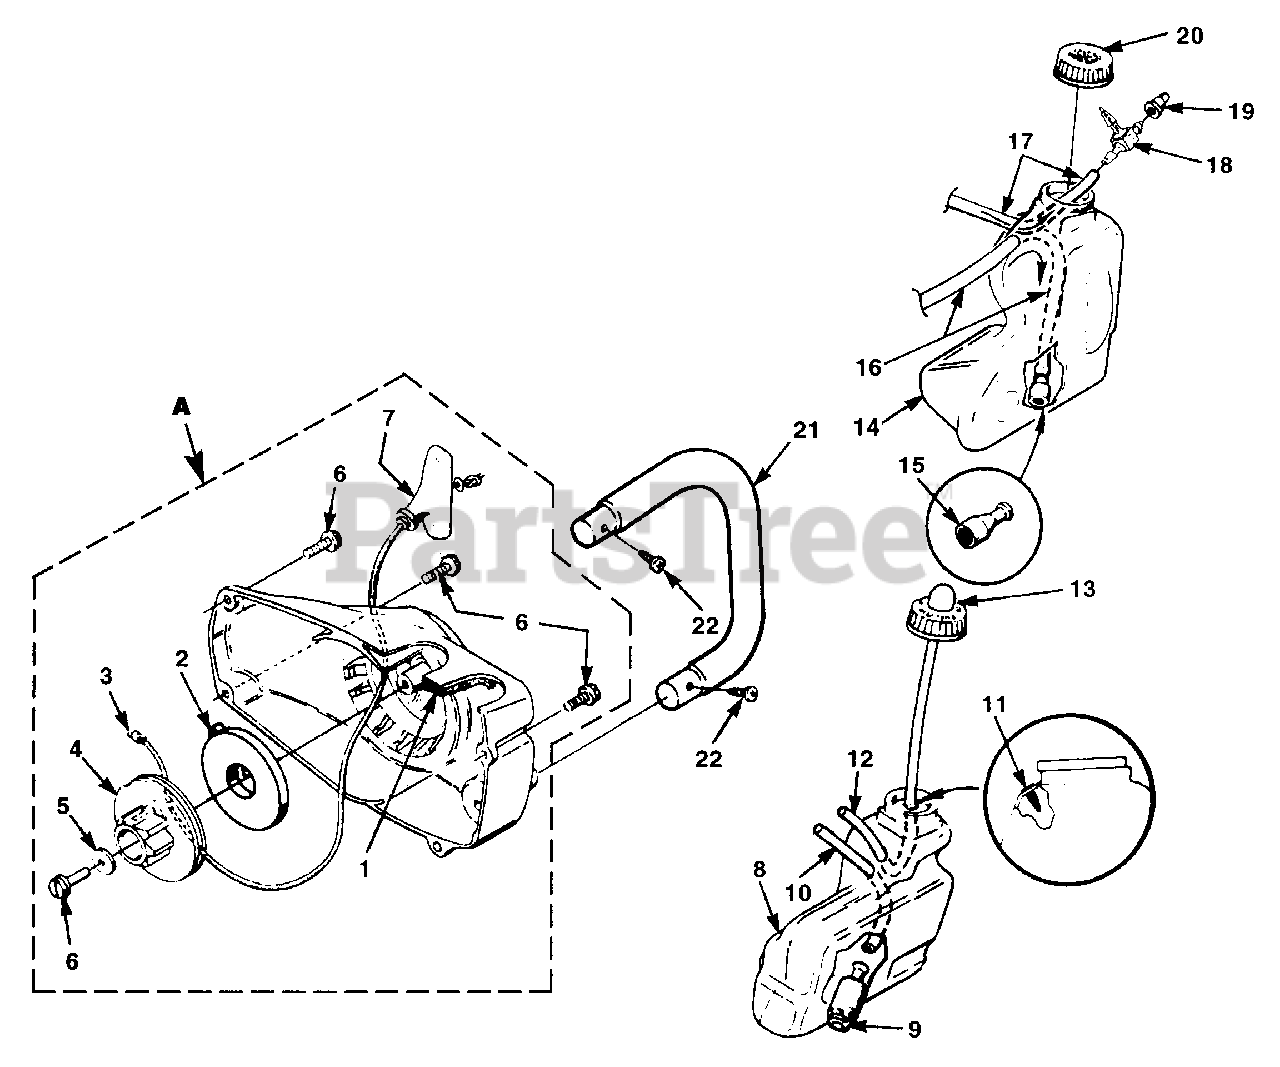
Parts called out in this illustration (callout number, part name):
2	SPRING & CONTAINER
3	ROPE - Starter (46")
4	PULLEY - Starter
5	WASHER - Retaining
6	SCREW - Torx (#10 X 3/4")
7	GRIP - Starter
8	FUEL TANK
9	FILTER - Fuel
10	LINE - Fuel (5 1/2")
11	VALVE - Duck Bill
12	TUBING - Return (6 1/4")
13	PRIMER & CAP
14	OIL TANK
15	FINDER - Oil
16	TUBING - Rubber (8")
17	TUBING - Rubber (5")
18	FITTING - Vent
19	VALVE - Check
20	OIL CAP
21	HANDLE BAR
22	SCREW - Pan Plastite (#10-16 X 3/4")
A	STARTER ASSY., Complete
